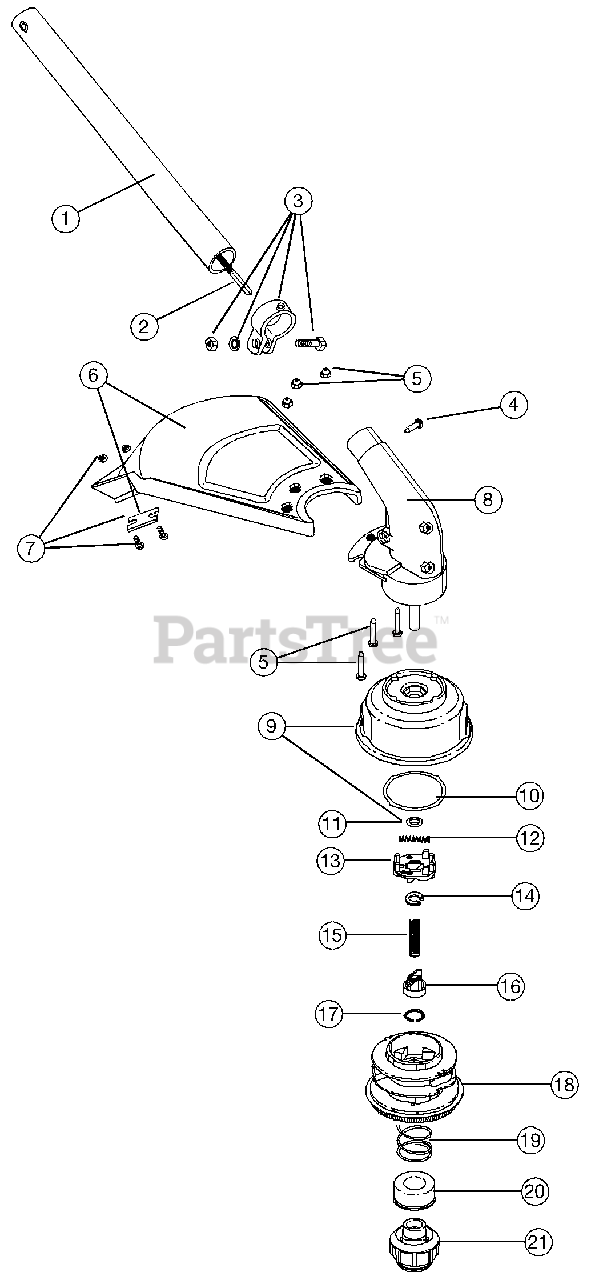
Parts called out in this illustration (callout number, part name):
1	Lower Drive Shaft Housing Assembly
2	Lower Flexible Drive Shaft
3	Lower Clamp Assembly
4	Anti-Rotation Screw
5	Shield Mounting Hardware
6	Shield and Blade Assembly
7	Blade Assembly
8	Gearbox Assembly
9	Outer Spool & Eyelet Assembly
10	Thrust Washer
11	Retaining Ring
12	Small Spring
13	Slider
16	Plunger
18	Inner Reel
19	Large Spring
20	Foam Seal
21	Bump Head Knob Assembly
